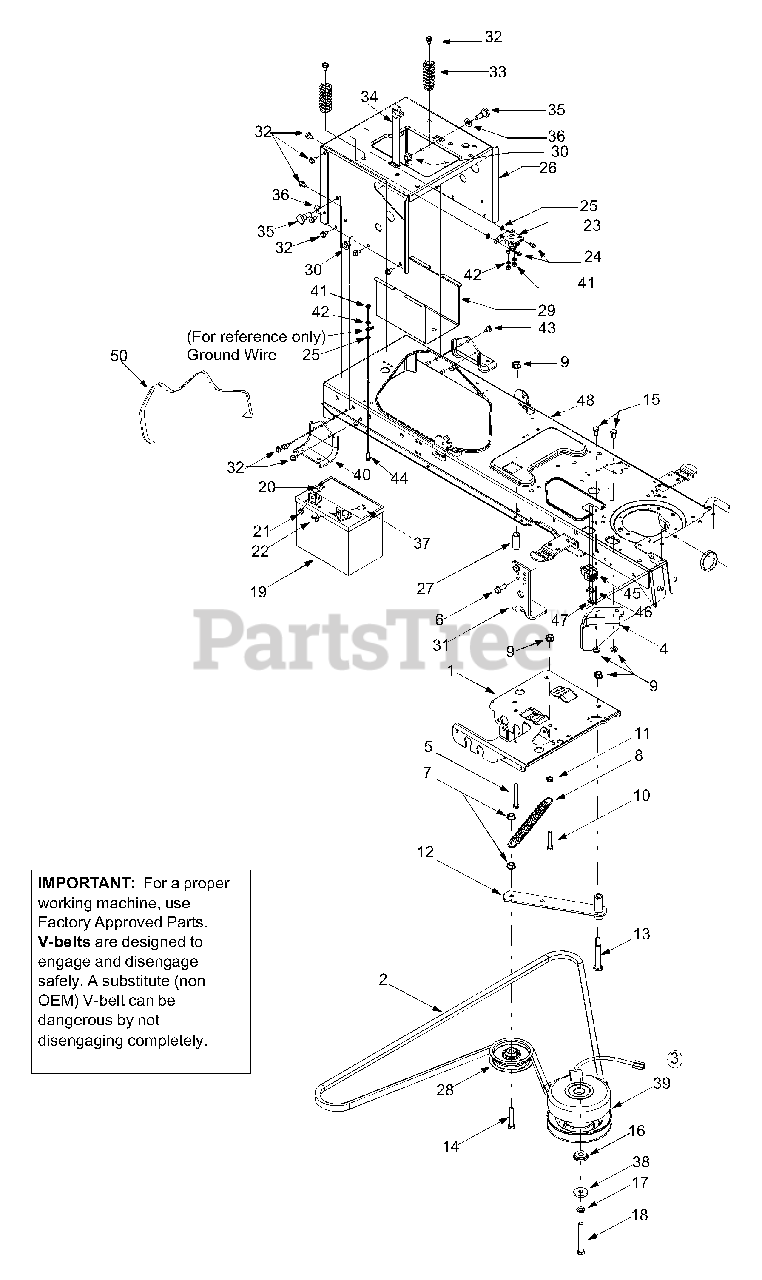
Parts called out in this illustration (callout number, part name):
2	PTO Belt
3	Elec. PTO Clutch
3	Washer, Flat, 1.031 x 1.620 x .095
6	Hex Hd Wash. Screw, 5/16-18 x .875
7	Lock Nut, 3/8-16
8	Extension Spring, .62 x 5.62
9	Flange Lock Nut, 5/16-18
10	Hex Cap Screw, 5/16-18 x 1.75
11	Hex Nut, 5/16-18
14	Hex Cap Screw, 3/8-16 x 2.0
15	Hex Cap Screw, 5/16-18 x .625
16	Shoulder Spacer, 1.38 x .445 x .36
17	Lock Washer, 7/16
18	Hex Cap Screw, 7/16-20 x 3.25
19	12-volt Battery, 270 CCA
20	Carriage Screw 1/4-20 x 0.75
21	Hex Sems Nut, 1/4-20
22	Wing Nut, 1/4-20
23	Solenoid, 12-Volt, 100 Amp
24	Self Tapping Screw, 1/4-20 x .5
25	Lock Washer, 1/4
28	Idler Pulley, 3.5
32	AB Screw, 5/16-12 x .75
33	Compression Spring
34	Battery Strap
35	Shoulder Screw, .625 x .5, 7/16-20
36	Bell Washer, .45 x 1.0 x .062
37	Shoulder Screw, 1/4-20, .25 x .15
38	Flat Washer, .45 x 1.25 x .164
39	Harness Assembly, PTO Clutch
41	Hex Nut 1/4-20
42	Lock Washer
43	TT Screw 5/16-18 x 0.5
44	TT Screw 1/4-20 x 0.75
45	Switch
46	Switch Plate
47	AB Screw #10-16 x 0.5
49	Lock Nut 3/8-16
50	Battery Hold-Down Rod
